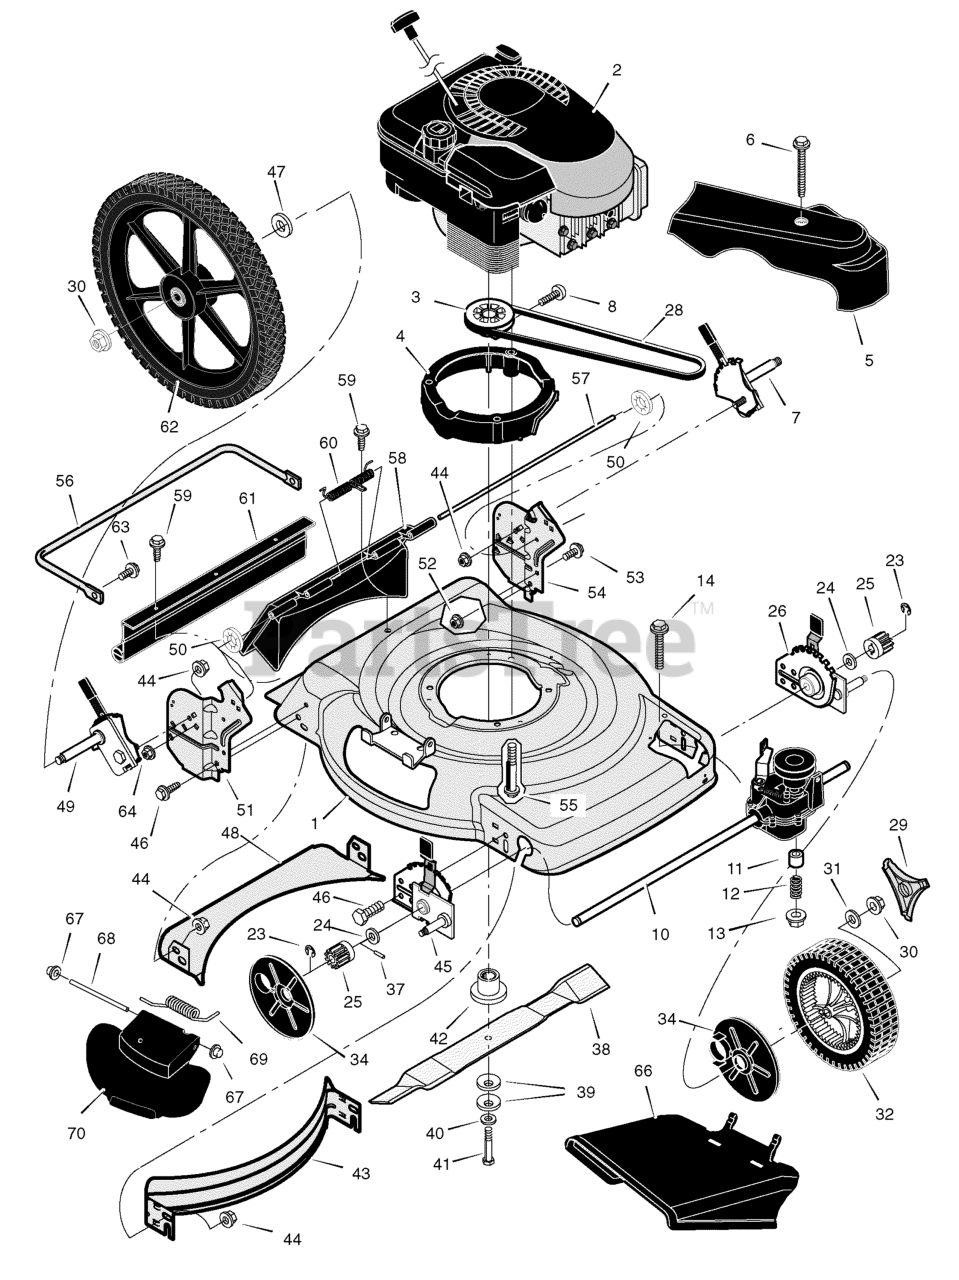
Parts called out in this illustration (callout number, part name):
2	Engine *
3	Pulley, Drive
4	Spacer, Engine
5	Cover, Belt (Black)
5	Cover, Belt (Gray)
7	Adjuster, Left Rear Height
10	Transmission *
11	Spacer
12	Spring, Compression
13	Nut
14	Bolt
23	E-Ring
24	Washer
25	Gear, Pinion
26	Adjuster, Left Front Height
29	Cap, Hub (Gray)
30	Nut, Flange
31	Washer
32	Wheel & Tire, Front (Gray)
34	Cover, Dust
37	Pin, Drive
39	Washer, Belleville
40	Washer
42	Adapter, Blade
43	Baffle, Front
44	Nut, Flange
45	Adjuster, Right Front Height
46	Bolt
47	Washer
48	Baffle, Rear *
49	Adjuster, Right Rear Height
50	Retainer, Push
51	Bracket, Right Handle
52	Nut, Flange
53	Bolt
54	Bracket, Left Handle
55	Bolt, Engine
57	Rod, Pivot
58	Door, Rear (Black)
58	Door, Rear (Gray)
60	Spring
61	Guard, Rear
62	Wheel & Tire, Rear (Gray)
63	Bolt
66	Deflector, Chute (Black)
66	Deflector, Chute (Gray)
67	Push On Cap
68	Rod, Pivot
69	Spring, Torsion
70	Cover, Mulch (Black)
70	Cover, Mulch (Gray)
